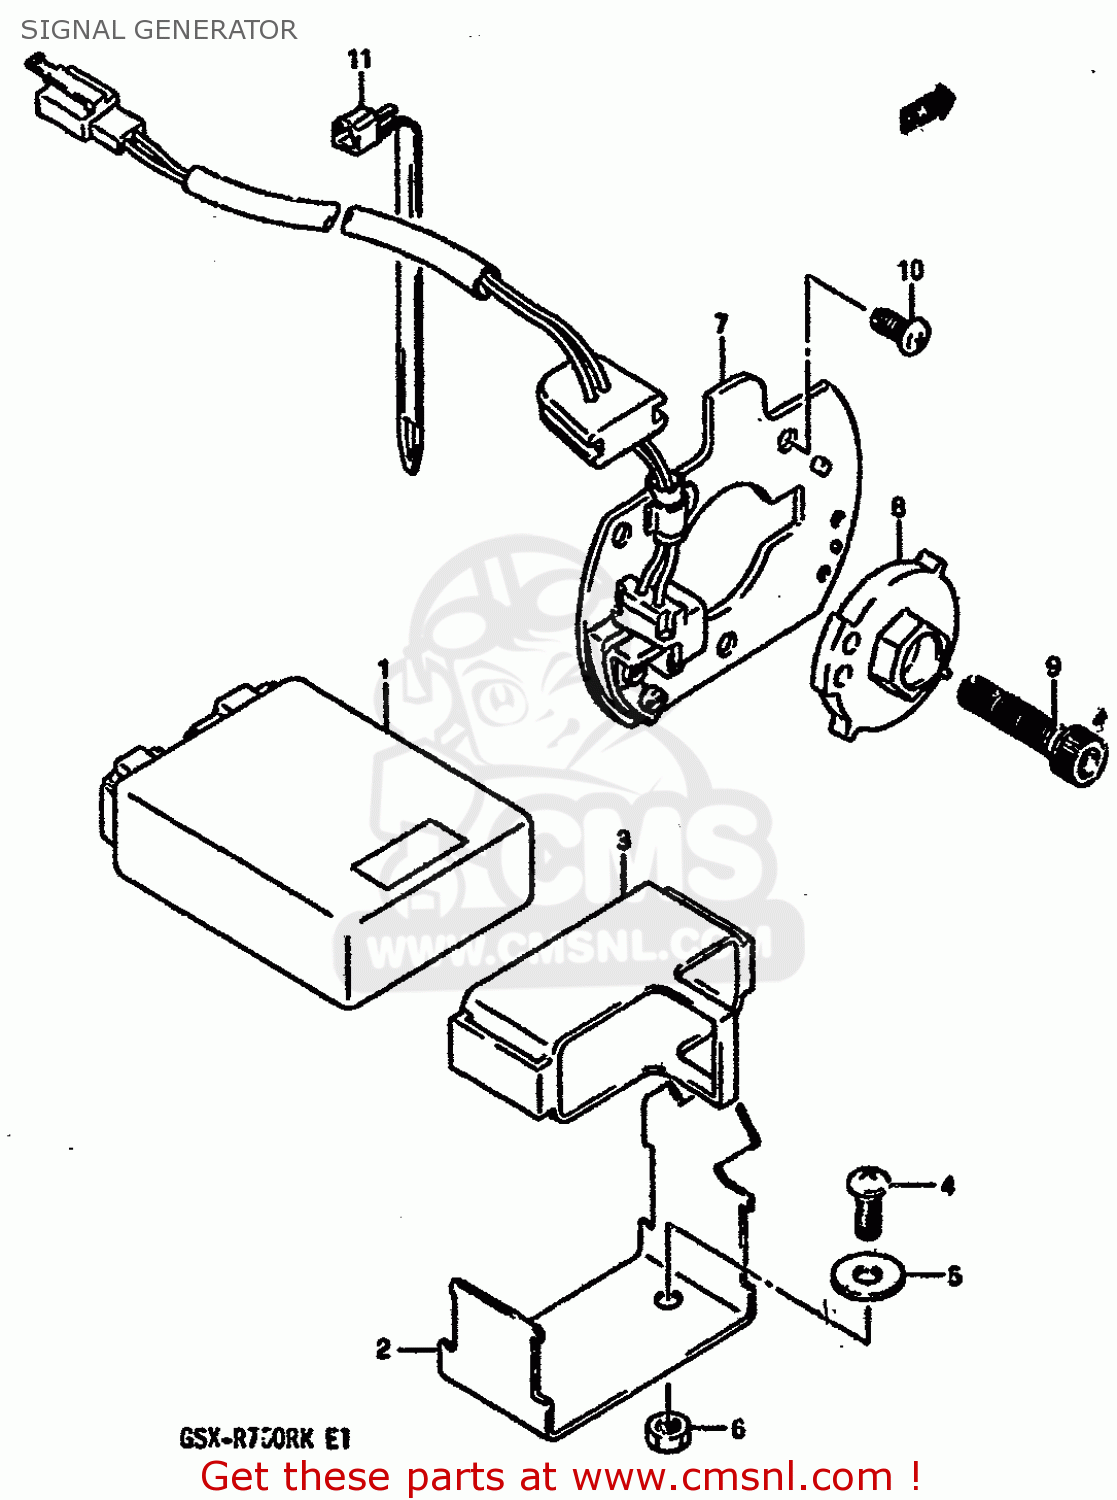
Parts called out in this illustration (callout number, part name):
1	IGNITER UNIT
2	BRACKET
3	CUSHION,IGNITER
4	SCREW
5	WASHER
6	NUT
7	SIGNAL GENERATOR ASSY
8	ROTOR,SIGNAL
9	BOLT
10	SCREW
11	CLAMP(L:125)
